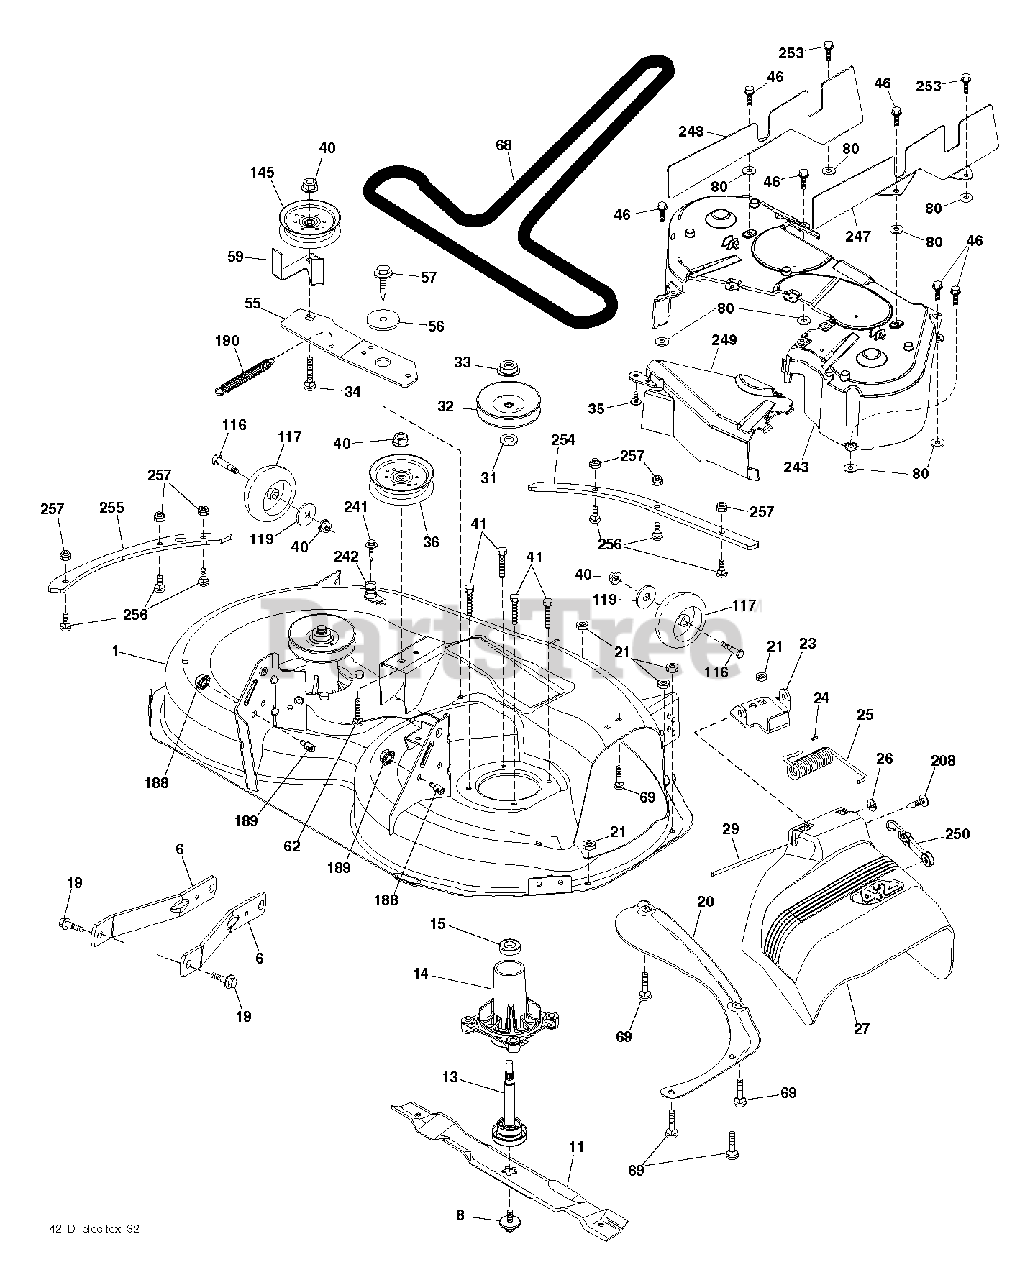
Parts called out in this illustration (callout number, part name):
1	DECK SVC 42"B 103 419175X498
6	ARM.SUSPENSION.MOWER.R
8	SCREW 7/16 X 20 X 1" HEX HEAD
11	42" HI-LIFT BLADE
13	RB MANDREL.ASM.SUB-NON.GR
14	HOUSING.MANDREL.REV.TALL.N/GRS
19	BOLT.SHOULDER
20	BAFFLE.VORTEX
21	LOCKNUT
23	BRKT.DEFLECTOR.38"2005+
24	CAP-SLEEVE LT
25	SPRING.TORSION.DEFLECT
26	NUT PUSH M
27	DEFLECTOR ASM.42"TEX.FRENCH
29	ROD.HINGE
31	WASHER.SPACER.MANDREL
32	PULLEY/MANDREL
33	NUT.FLANGE.LOCK.TOP
34	BOLT.3/8-16X1.50
35	FASTENER.XMAS.TREE
36	PULLEY.IDLER.2006
40	NUT LOCK FLG 3/8-16 UNC
41	BOLT.HEX.WASHR.HED.313-18X1.19
46	SCREW.1/4-20X5/8
55	IDLER.ARM.42"
56	SPACER.RETAINER
57	SCREW 3/8-16X1
59	GUARD, BELT
68	BELT V SECONDARY
69	BOLT
80	PALNUT 1/4
116	BOLT M
117	WHEEL.GAGE.HALF.SPOKED
119	WASHER
145	PULLEY.IDLER.48"PRIMARY
188	STUD.FASTNER.W/ANTI-ROTATE
189	NUT LOCK HEX FLANGE 5/16-18
190	SPRING.MOWER.DRIVE.ELECTRIC
208	SCREW 3/8-16X1/2
241	SCREW.TT.#10-32X.5.3/8.FLANGE
242	PORT.WASHOUT
243	COVER DECK
247	SHIELD DECK RIGHT
248	SHIELD DECK LEFT
249	COVER CABLE CLUTCH
250	ELASTIC STRAP KIT
253	SCREW
254	PLATES.RENFRC.42DECK.PT431FRNT
255	PLATES.RENFRCE.42DECK.X431SIDE
256	RHSNB, 1/4-20 X 1, GR5
257	NUT T
